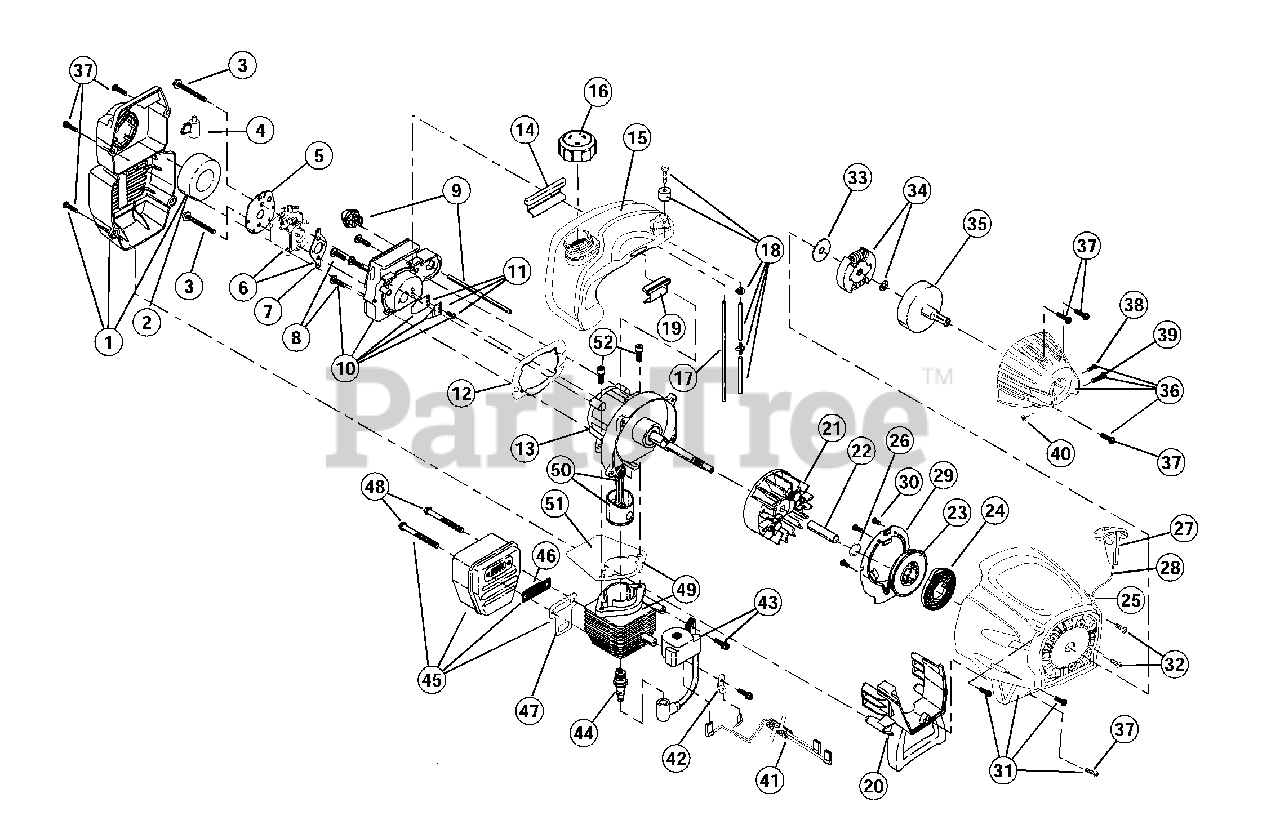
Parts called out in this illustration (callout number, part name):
1	Air Cleaner/Muffler Cover Assembly
2	Air Cleaner Filter
3	Carburetor Mounting Screw Assembly
4	Choke Extension
5	Choke Plate
6	Carburetor Assembly
7	Carburetor Gasket
8	Carb Mount Screw
9	Primer and Hose Assembly
10	Carb Mount Assembly
11	Reed Assembly
12	Carburetor Mount Gasket
13	Crank Case Service Assembly
14	Rear Mounting Pad
15	Fuel Tank Assembly
16	Fuel Cap Assembly
17	Fuel Return Line
18	Fuel Line Assembly
19	Front Mounting Pad
20	Shroud Extension and Stand
21	Flywheel Assembly
23	Recoil Pulley
24	Recoil Spring
25	Rope Guide
26	Pulley Retainer
27	Pull Handle
29	Pressure Plate Assembly
30	Plate Screw
31	Starter Housing Assembly
32	Housing Screw
33	Clutch Washer
34	Clutch Rotor Assembly
35	Clutch Drum Assembly
36	Clutch Cover Assembly
37	Cover Screw
38	Anti-Rotation Screw
39	Clamping Screw
40	Clamping Nut
41	Wire Leads and Sleeve
42	Ground Tab
43	Module Assembly
45	Muffler Assembly
46	Spark Arrestor Screen
47	Exhaust Gasket
48	Muffler Mounting Bolt Assembly
49	Cylinder Assembly
50	Piston and Rod Assembly
51	Cylinder Gasket
52	Cylinder Bolt
